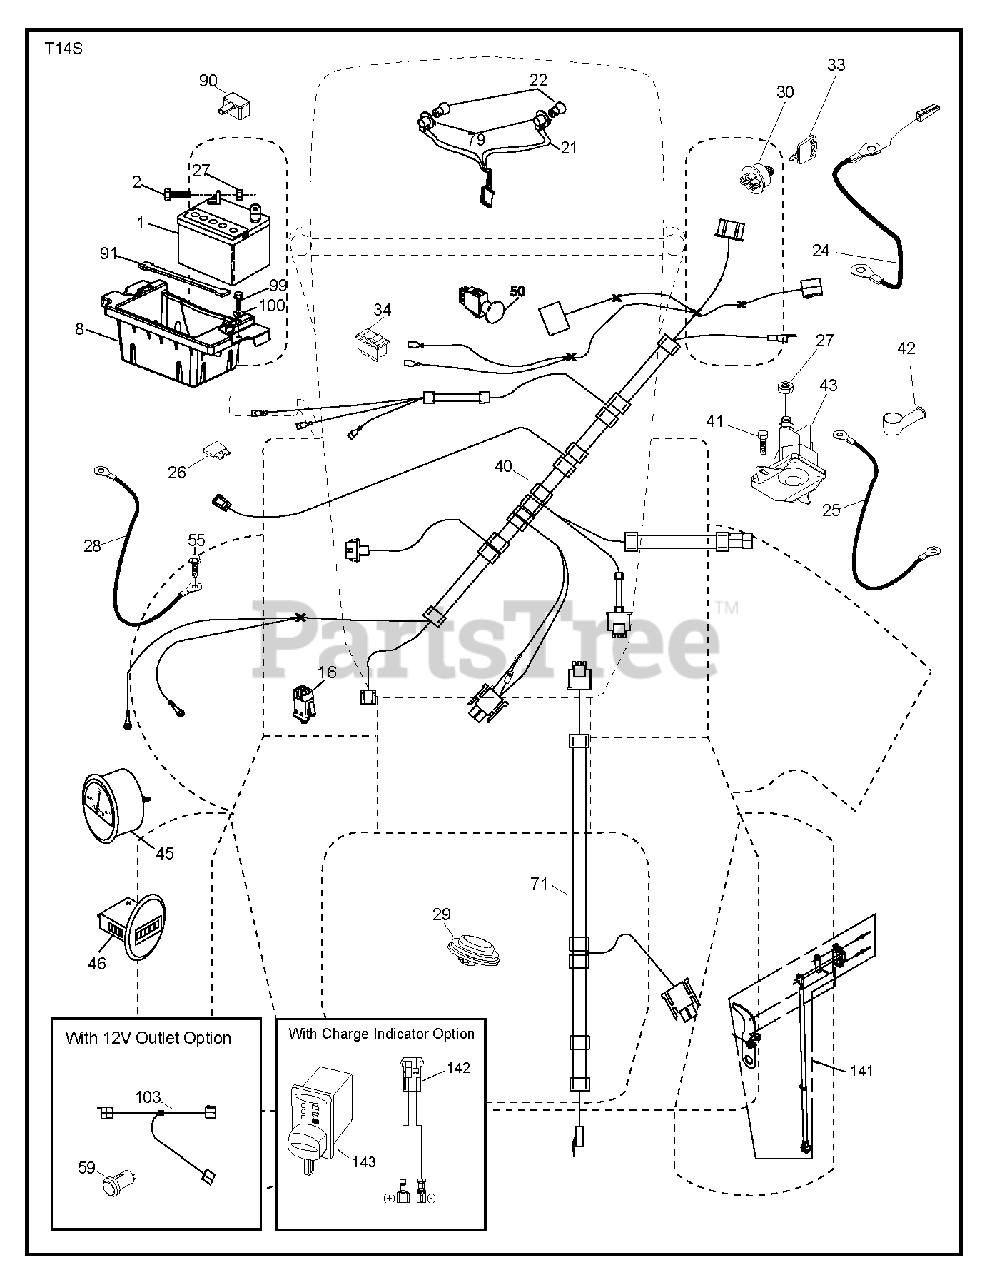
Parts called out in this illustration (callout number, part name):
1	Battery, Dry 30 Amp
2	BOLT.HEX.1/4.X.3/4.DICHROMATE
8	BOX.BATTERY.MOUNT.FRONT.LT
16	SWITCH INTERLOOK PUSH-IN
21	HARNESS.LIGHT W/4152J BULBS
24	CABLE.BATT.POS.WIRE.TG.DA SOL
25	CABLE.STARTER.6G.BL/RED.17.5
26	FUSE 20AMP
27	NUT
28	CABLE GROUND 6 GA 21" 90T BLK
29	SWITCH.SEAT.DELTA.OPC.
30	SWITCH.IGN.DELTA.W.LGH.ROS
33	KEY.CHAIN.BLISTER.PACK.GEN.USA
40	HARNESS.IGN.DASH.W/112V.PORT
41	SCREW
42	TERMINAL COVER
43	SOLENOID.W/BRASS.PLUNGER
45	AMMETER GAUGE ROUND SNAP-IN
46	HOURMETER.GAUGE.RNK.SNAPIN.LS
50	RB PTO.SWITCH.8 TERMINAL.BLACK
55	SCREW 5/16"
59	OUTLET.12-VOLT
71	HARNESS-CHASSIS SUB
79	BULB HOLDER ASM.
90	COVER.TERMINAL.BATTERY
91	STRAP.BATTERY.MOUNT.FRONT(2 2)
99	SCREW HEXWSHR 1/4-20X3/4
103	HARNESS.PIGTAIL.12V.OUTLET.
141	KIT.G700/G730.ROS 71750
142	CHARGE.PORT.PIGTAIL HARNESS
143	CHARGE.PORT
